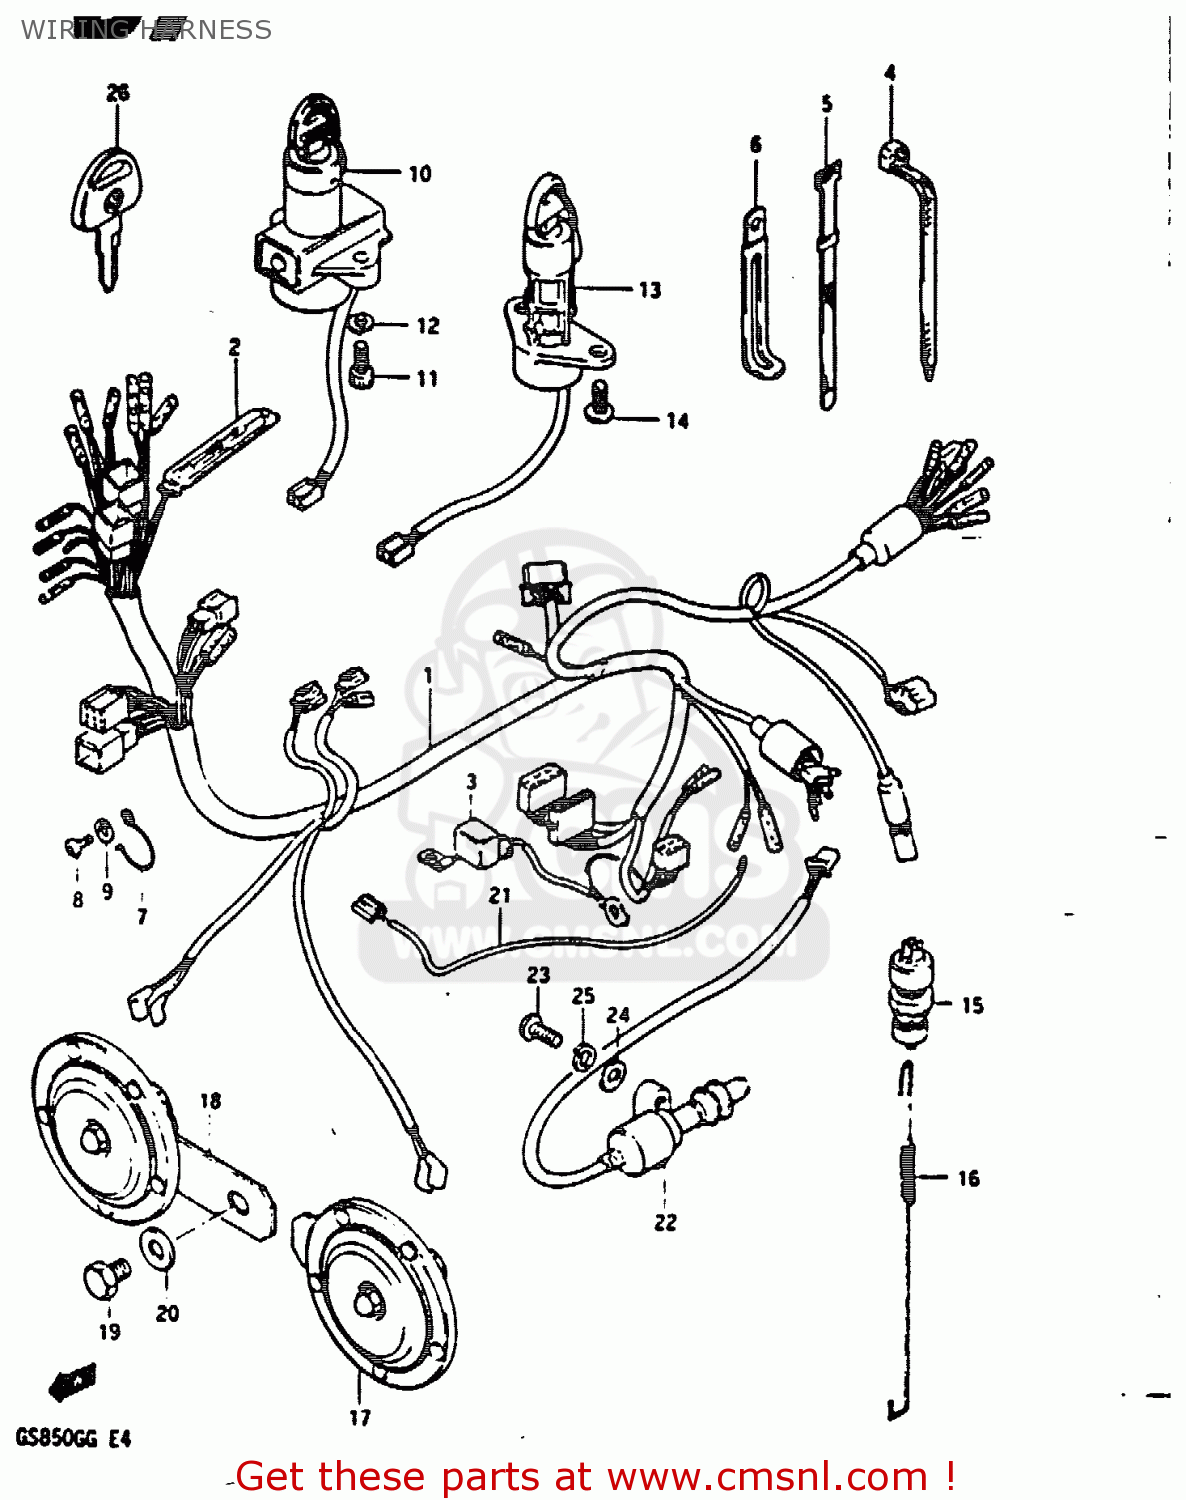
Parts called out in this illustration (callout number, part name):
1	WIRING HARNESS
2	DIODE
3	CAP, BATTERY (+) TERMINAL
4	CLAMP(L:165)
5	CLAMP(L:120)
6	CLAMP
7	CLIP,WIRING HARNESS
8	SCREW
9	WASHER
10	SWITCH ASSY,IGNITION
11	BOLT
12	WASHER,LOCK
13	SWITCH ASSY,IGNITION
14	SCREW 6X12
15	SWITCH ASSEMBLY,STOP LAMP
16	SPRING
17	HORN ASSEMBLY,LOW PITCH
18	HORN ASSEMBLY,HIGH PITCH
19	BOLT
20	WASHER
21	WIRE,OIL PRESSURE SWITCH LEAD
22	SWITCH ASSY,SIDE STAND WARN
23	BOLT
24	WASHER
25	LOCK WASHER
26	KEY,BLANK
